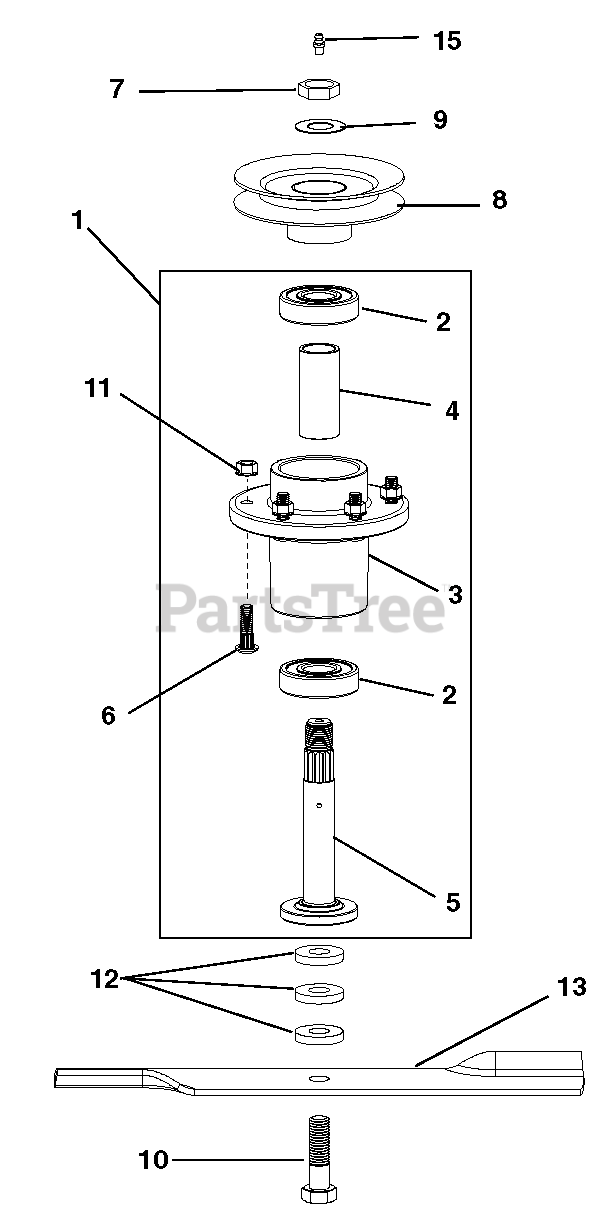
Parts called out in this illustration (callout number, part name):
1	Spindle Assembly (Includes 2, 3, 4, 5, 15)
2	Bearing, 6305LLC
3	Casting, Spindle w/Studs
4	Spacer, 1.250 x 1.000 x 2.780
5	Shaft, Spindle .75-16
6	Bolt, .38-16 x 1.25 Round Head Square Neck
7	Locknut, .75-16 Crown Y
8	Pulley, Cutter Housing -
9	Spacer, Spindle Top-Pulley
10	Bolt, 5/8-11 x 2.00 Hex 8
11	Nut, .38-16 Standard Hex Grade 5
12	Washer, .630 x 1.50 x .250 Flat
13	Blade, 18.000 x .80 Lift
14	Blade, 16.500 x .80 Lift
15	Zerk, Grease S/O
